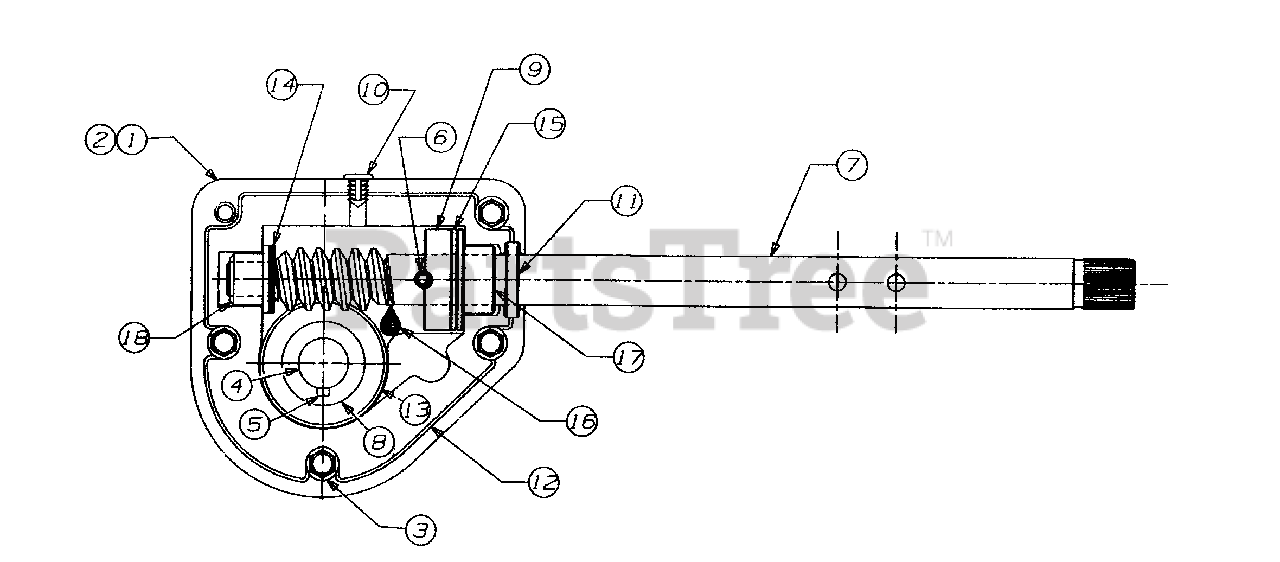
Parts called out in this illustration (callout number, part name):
1	Housing-L.H.
2	Housing-R.H.
3	Screw
4	Spiral Axle 22"
5	Key
6	Pin-Spiral
7	Shaft-Worm
8	Gear-Worm
9	Collar-Thrust
11	Seal-Oil
12	Locktite 5699
13	Washer-Flat
14	Washer-Flat
15	Washer-Flat
16	Grease
17	Bearing-Flange
18	Bearing-Flange
